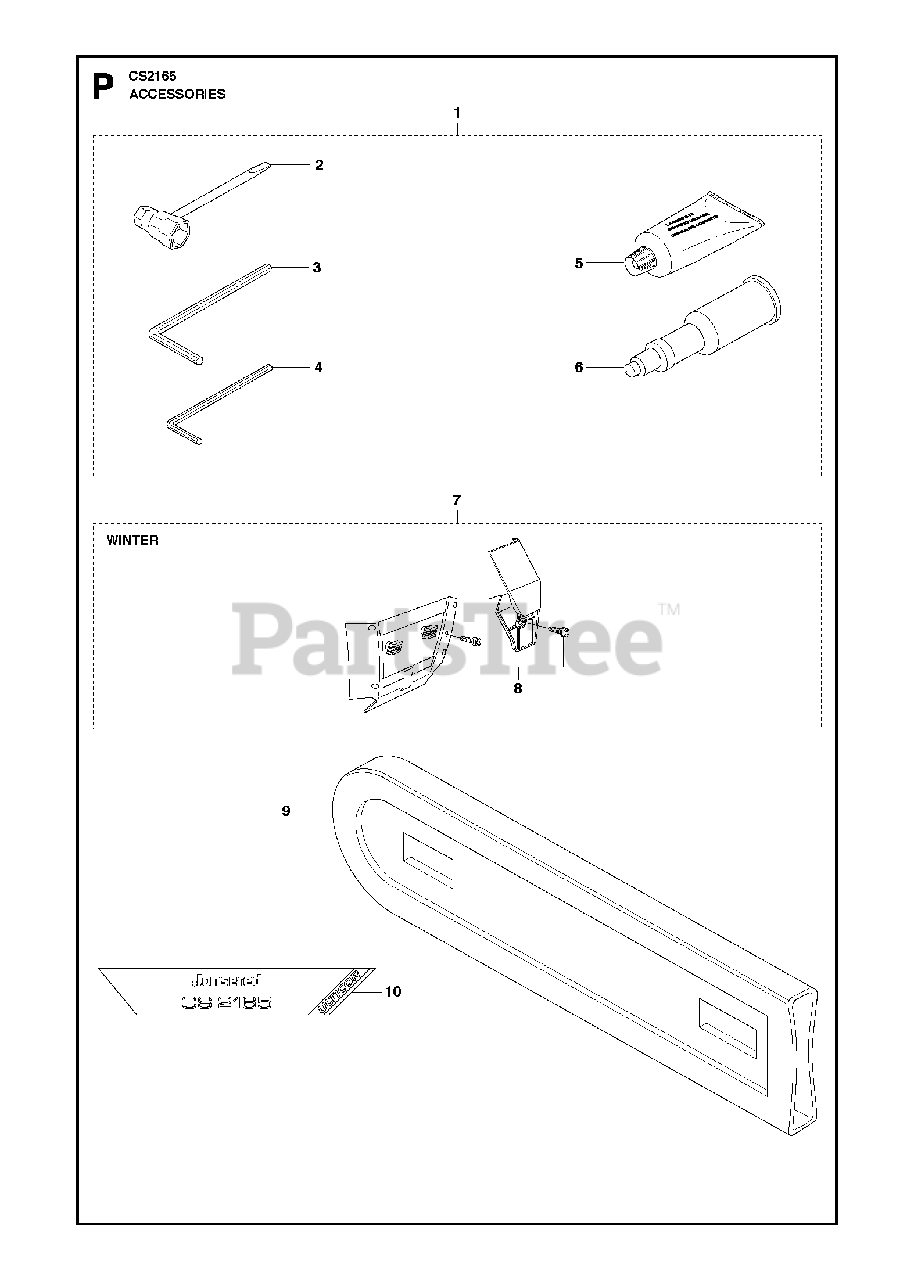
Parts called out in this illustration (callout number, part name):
1	TOOL KIT
2	COMBI TOOL
3	L-SPANNER
4	L-SPANNER
5	GREASE
6	GREASE GUN
7	WINTER SET
8	SCREW
9	BAR COVER
10	LABEL
